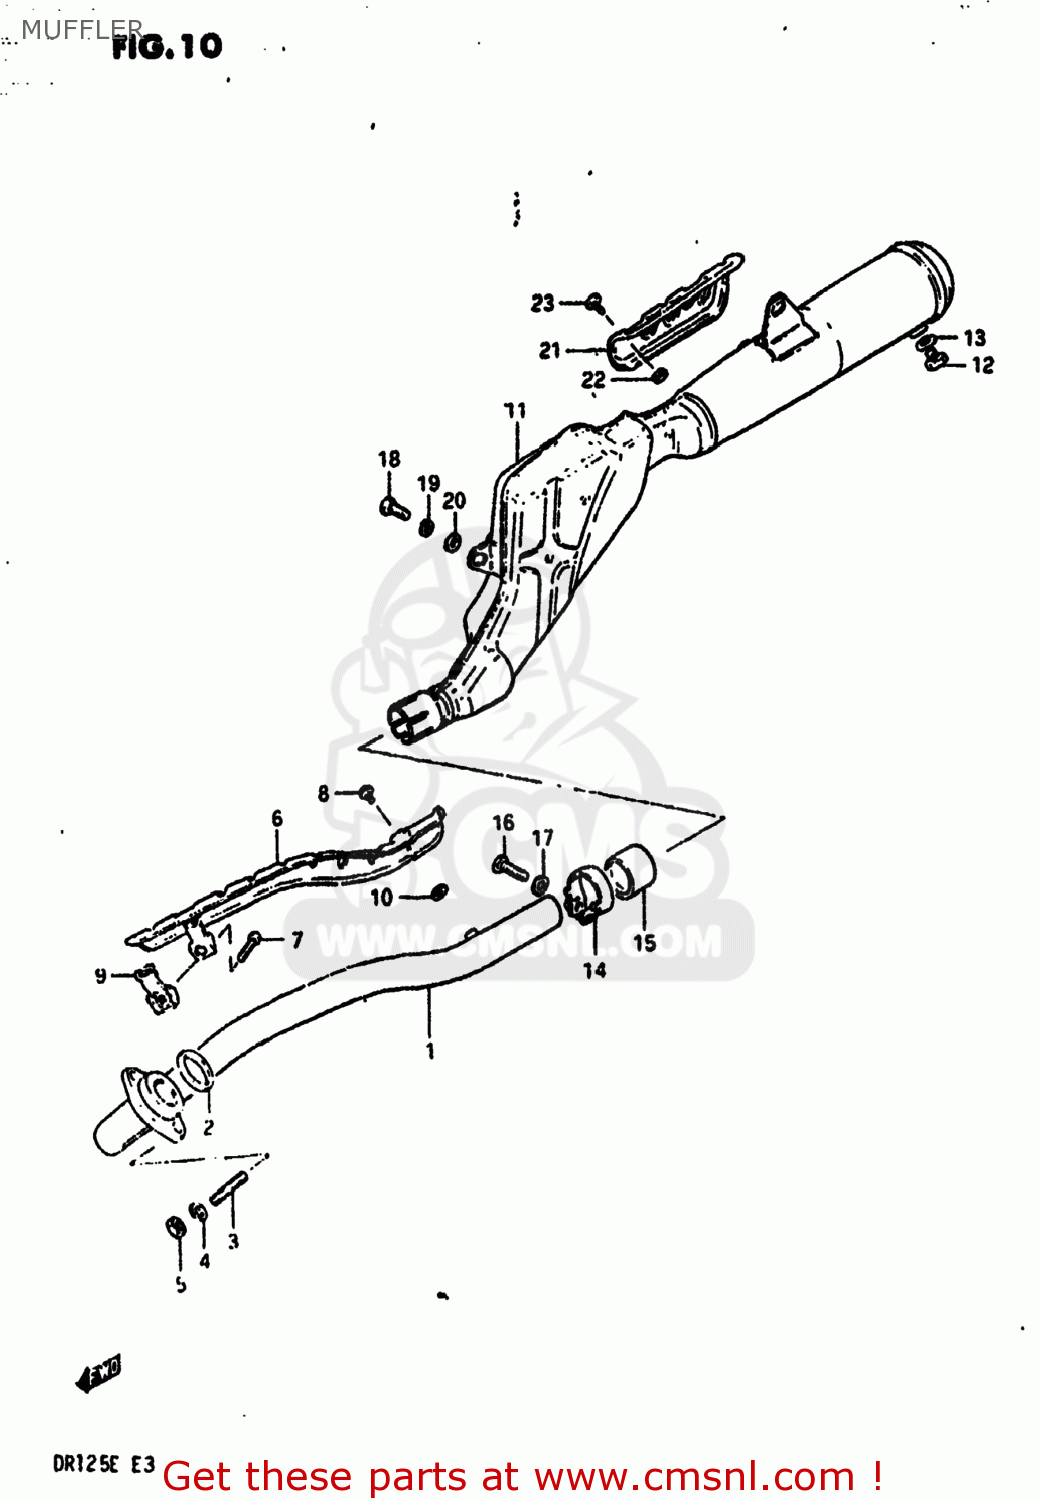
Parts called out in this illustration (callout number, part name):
1	PIPE,EXHAUST
2	GASKET,EXHAUST PIPE (NAS)
3	STUD BOLT L:20
4	LOCK WASHER
5	NUT
6	COVER,EXHAUST PIPE
7	SCREW 5X20
8	SCREW
9	CLAMP,EXHAUST PIPE COVER
10	GASKET 6.2X12X1.5 (MCA)
11	MUFFLER ASSEMBLY
12	PLUG(12X9)
13	GASKET(12X16X2) (NAS)
14	CLAMP,MUFFLER CONNECTOR
15	CONNECTOR,MUFFLER
16	BOLT 8X35
17	WASHER,8.5X16X
18	BOLT
19	LOCK WASHER
20	WASHER,8.5X16X
21	COVER,MUFFLER
22	GASKET 6.2X12X1.5 (MCA)
23	SCREW
